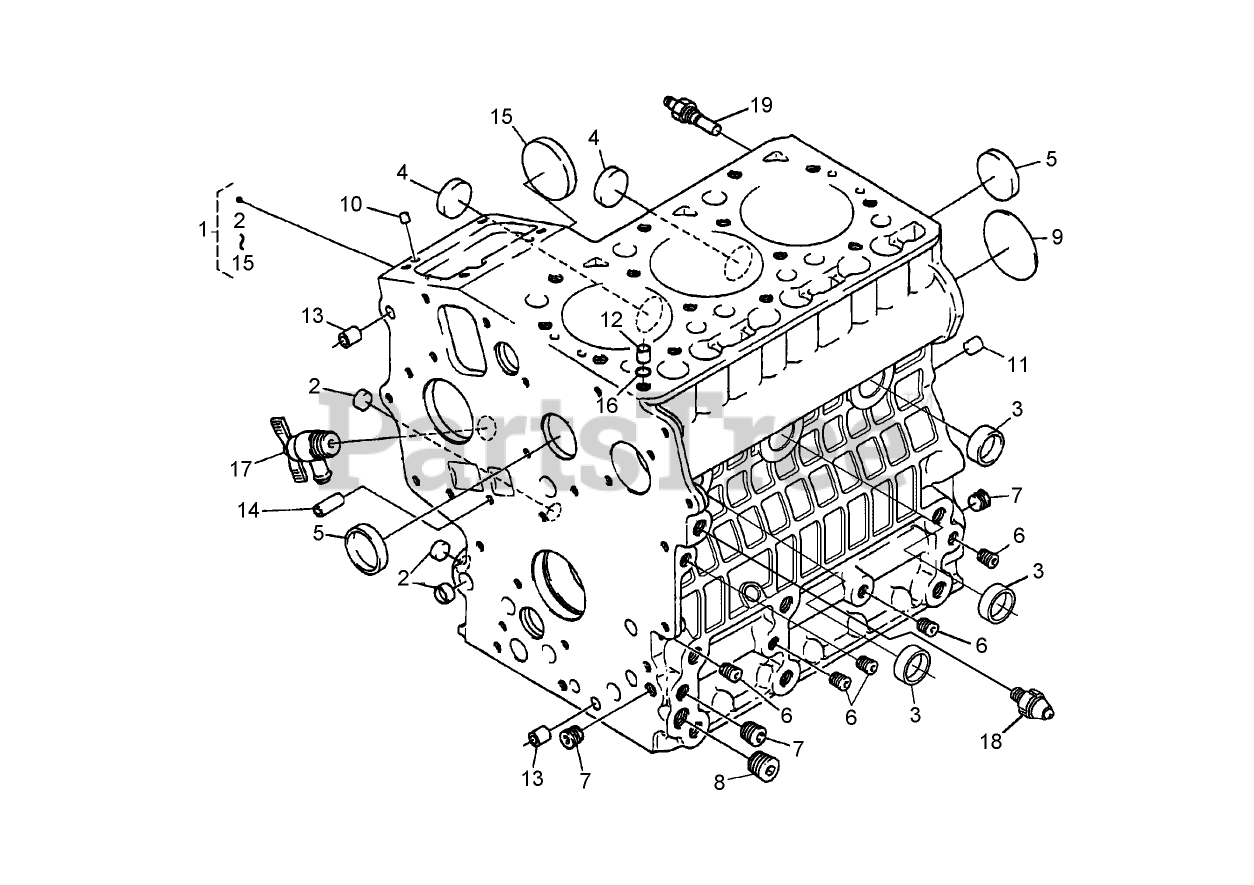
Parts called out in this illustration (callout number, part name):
1	CRANKCASE
2	CAP-SEALING
3	CAP-SEALING
4	CAP-SEALING
5	CAP-SEALING
6	PLUG
9	PLUG-EXPANSION
10	PIN-STRAIGHT
11	PIN-STRAIGHT
12	PIN-PIPE
13	PIN-PIPE
14	PIN-PIPE
15	COVER-FUEL, CAMSHAFT
16	O-RING
17	DRAIN COCK ASM
18	SWITCH-OIL
19	THERMOSWITCH
